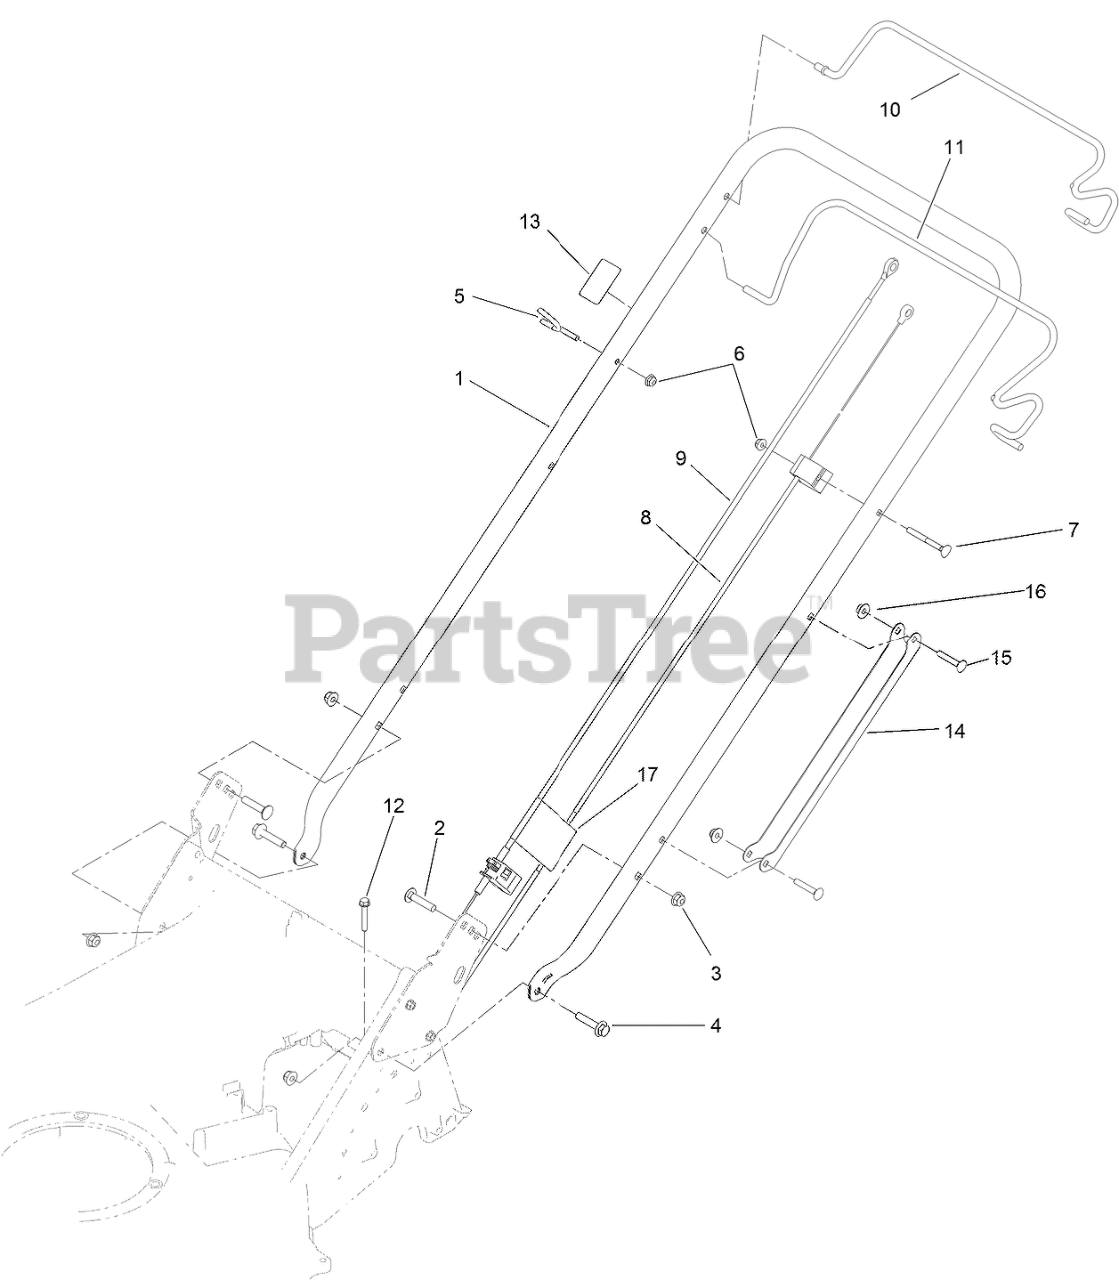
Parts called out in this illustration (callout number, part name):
1	HANDLE
2	BOLT-CARR
3	NUT-HF, NI
4	SCREW-HHF
5	GUIDE-ROPE
6	NUT-HF
7	SCREW-HANDLE
8	CABLE-BRAKE
9	CABLE-TRACTION
10	BAIL-TRACTION
11	BAIL-BRAKE
12	SCREW-HWH
13	DECAL-PRIMER
14	GUARD-CABLE, HANDLE
15	SCREW-CARR
16	NUT-HEX FLG
17	DECAL-ADJUST, SELF PROPEL DRIVE
